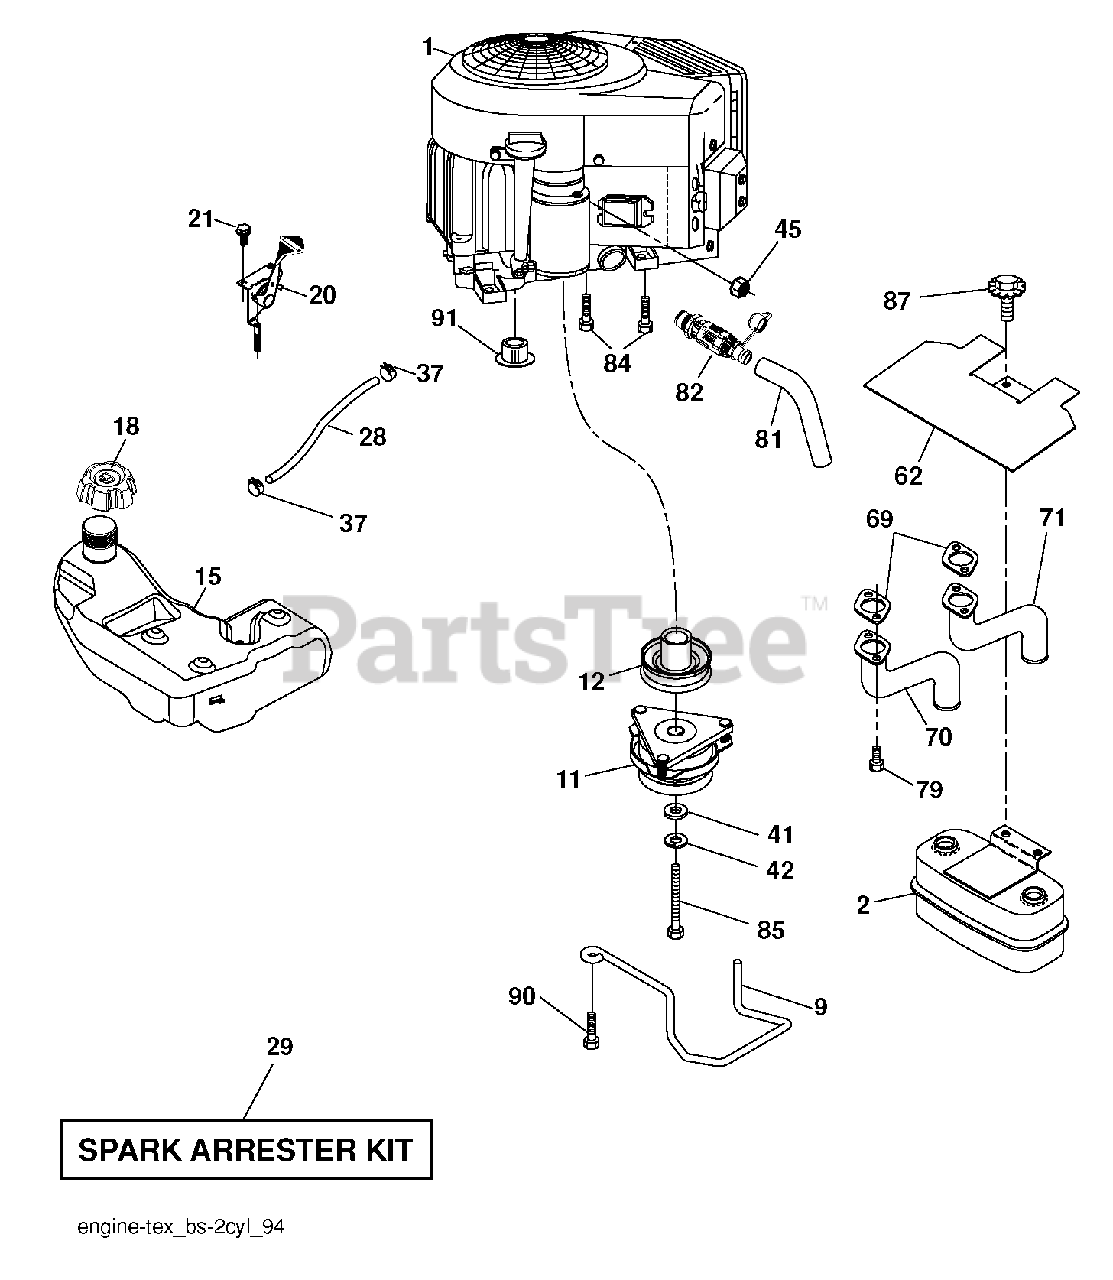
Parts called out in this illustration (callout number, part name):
2	MUFFLER.TWIN.CYL.LOW.TONE
9	KEEPER.BELT.ENGINE.4.2
11	CLUTCH.ELECTRIC.LT.48"*
12	PULLEY.ENGINE.TUFFTORQ
15	TANK.ASSY.3.GAL.EPA
18	CAP ASM.FL.RTCHT.3"GRY.E10
20	CONTROL.TH/CK.COBRA.B&S.TWN.
21	SCREW.#10 X 0.750.BOS (2 2)
28	LINE.FUEL.64"REAR.EMIS
29	SPARK ARRESTOR KIT
37	HOSE CLAMP
42	LOCKWASHER
45	NUT
62	SHIELD.HEAT.MUFFLER
69	GASKET.MUFFLER
70	RP.EXHAUST.TUBE.LH.BS/TWIN
71	RP.EXHAUST.TUBE.RH.BS/TWIN
79	SCREW.SOCKET.HEAD.5/16-18
81	TUBE, DRAIN OIL ASM.
82	VALUE.OIL.DRAIN
84	SCREW.3/8-16
85	BOLT HEX 7/16-20X4-1/4"
87	BOLT, 5/16-18 X 1 3/4
90	SCREW 3/8-16X1
91	BUSHING.1.375OD
